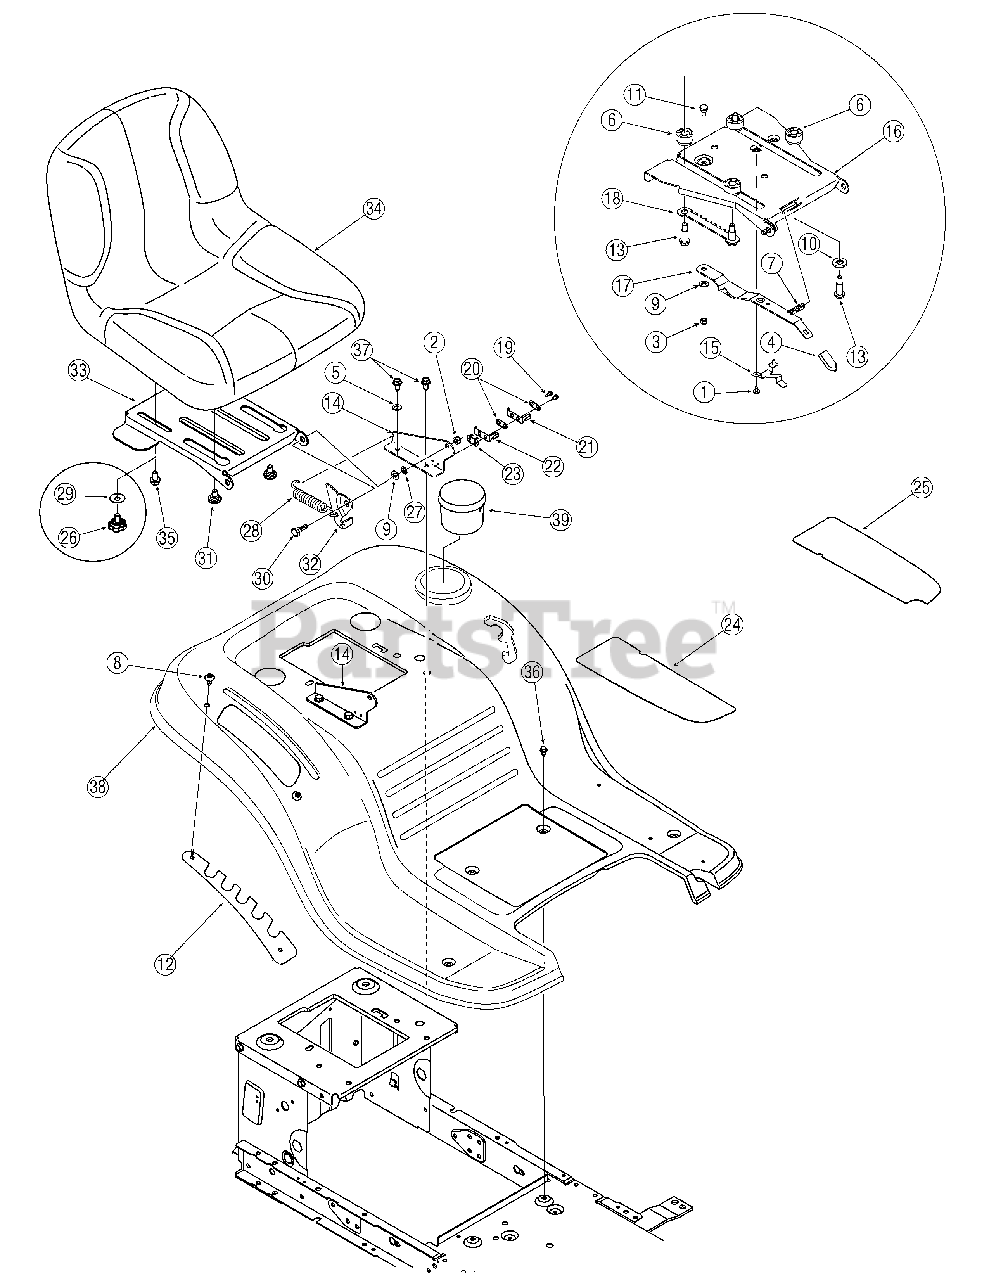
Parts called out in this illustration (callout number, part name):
1	Screw, #10-16, .375
2	Nut, Flange Lock, 5/16-18, GrF
3	Nut, Flange Lock, 1/4-20
4	Seat Adjuster Grip
5	Lock Washer, 5/16
6	Spacer
7	Compression Spring, .41 x 1.5
8	Screw, 1/4-20 x .500
9	Wash, Flat, .344 x .688 x .065
10	Wash, Flat, .531x 1.062 x. .134
11	Screw, Shlder, .340 x .285,1/4-20
13	Screw, Shlder, .50 x .925, 3/8-16
15	Seat Stop
18	Seat Adjustment Selector
19	Screw, #8-18 x .50
20	Plate, Insulator
21	Spring Switch, Outer
22	Spring Switch, Inner
23	Plate, Insulator Boss
24	Foot Pad, Abrasive, RH
25	Foot Pad, Abrasive, LH
26	Knob, 3/8-16, .625
27	Nut, Speed, .3125 Id
28	Spring, Exten., .84 Dia x 4.6 Lg
29	Washer, Flat, .406 x 1.00 x .030
30	Scr., Shlder, .437 x .268, 5/16-18
31	Screw, Shlder, .625 x .175, 3/8-16
32	Lift Bracket, Seat
34	Seat, Low Back
34	Seat, Medium Back
35	Screw, 3/8-16, .875
36	Screw, 1/4-20, 0.500
37	Screw, 5/16-18, 0.625
39	Cup Holder
